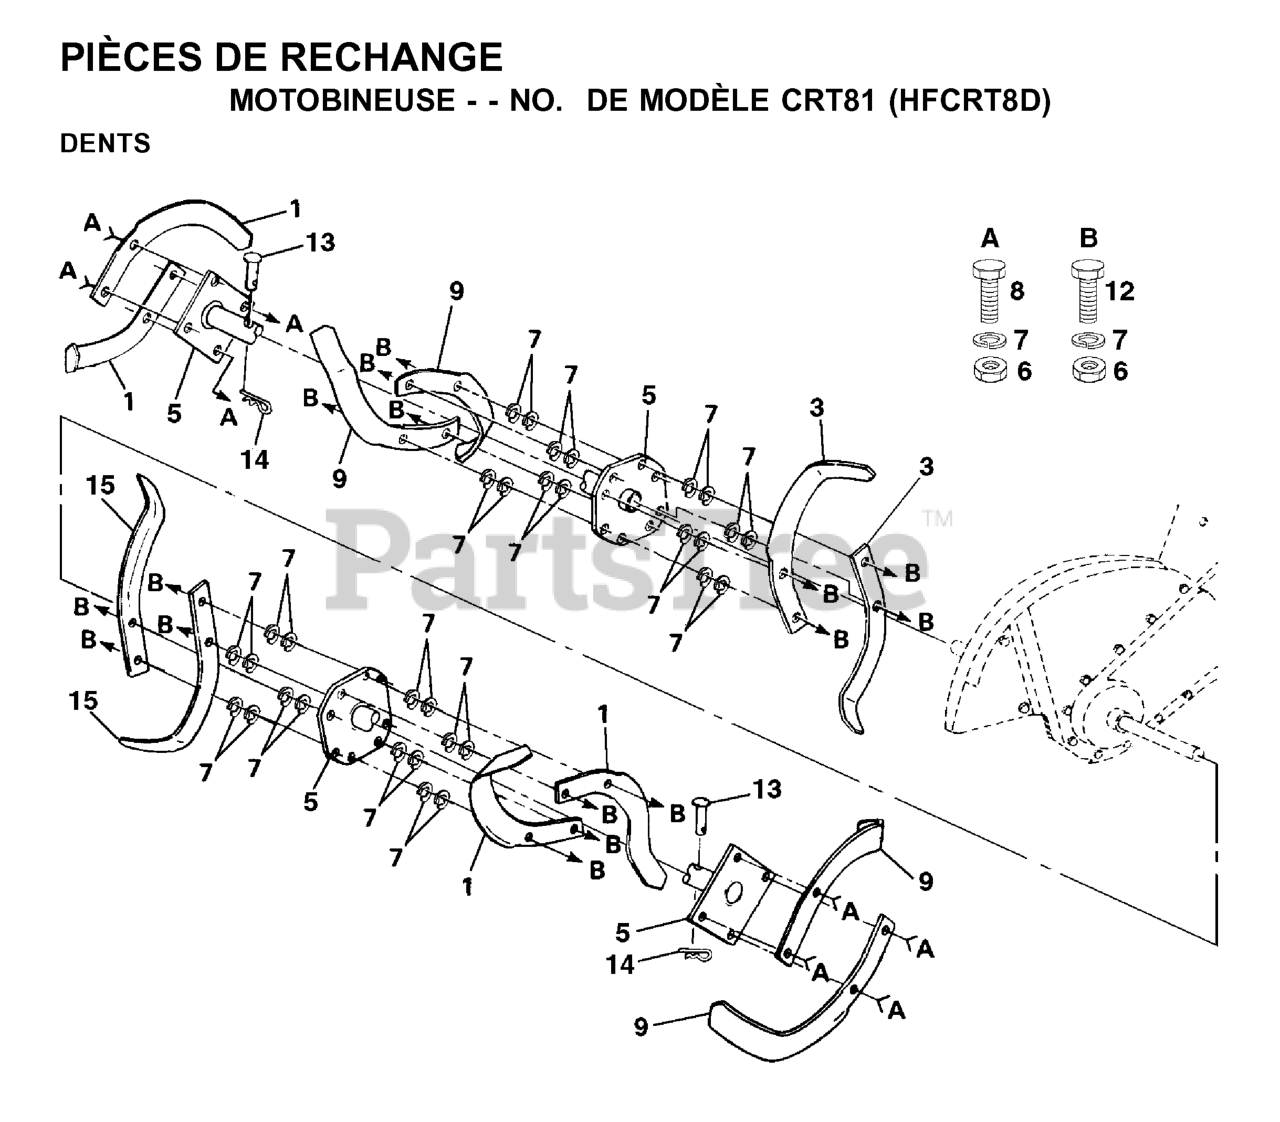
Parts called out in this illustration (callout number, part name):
1	TINE, LH 14"
3	TINE.LH.14".CRT
5	DNO HUB ASMBLY
6	NUT
7	WASHER, LOCK 3/8
8	BOLT.HEX.001X20.37-24X1.ZINC
9	TINE, RH 14"
12	BOLT.3/8-24X1-1/2
15	TINE.RH.14".CRT
